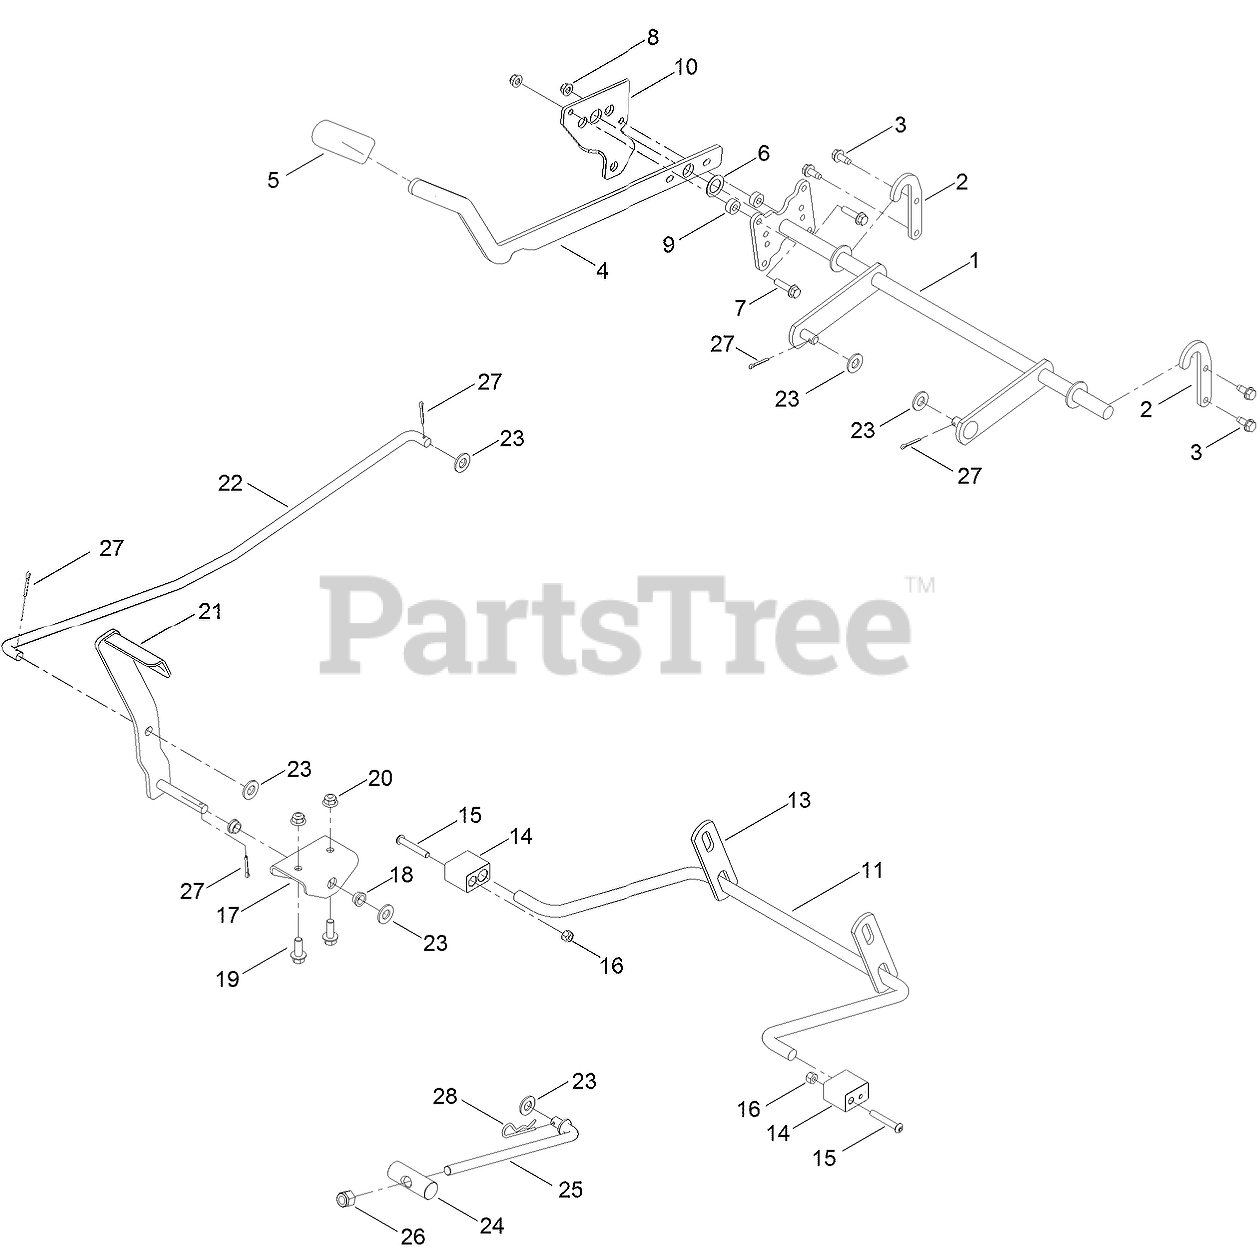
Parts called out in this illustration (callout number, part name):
1	LIFT-DECK, NARROW
2	BRACKET-LIFT
3	SCREW-HWHTF
4	LEVER-LIFT
5	GRIP-LEVER
6	WASHER-THRUST
7	SCREW-HHF
8	NUT-HF, NI
9	SPACER
10	PLATE-FOOTLIFT
11	ARM-LIFT, REAR
13	LINK-LIFT
14	BLOCK-PIVOT
15	SCREW-HSBH
16	NUT-LOCK, NI
17	BRACKET-FOOTLIFT
18	BUSHING-FLANGE
19	SCREW-HHF
20	NUT-HF, NI
21	PEDAL ASM
22	ROD-FOOTLIFT
23	WASHER-FLAT
24	PIN-PIVOT
25	ROD-MOUNT, DECK
26	NUT-HEX
27	PIN-COTTER
28	PIN-COTTER
